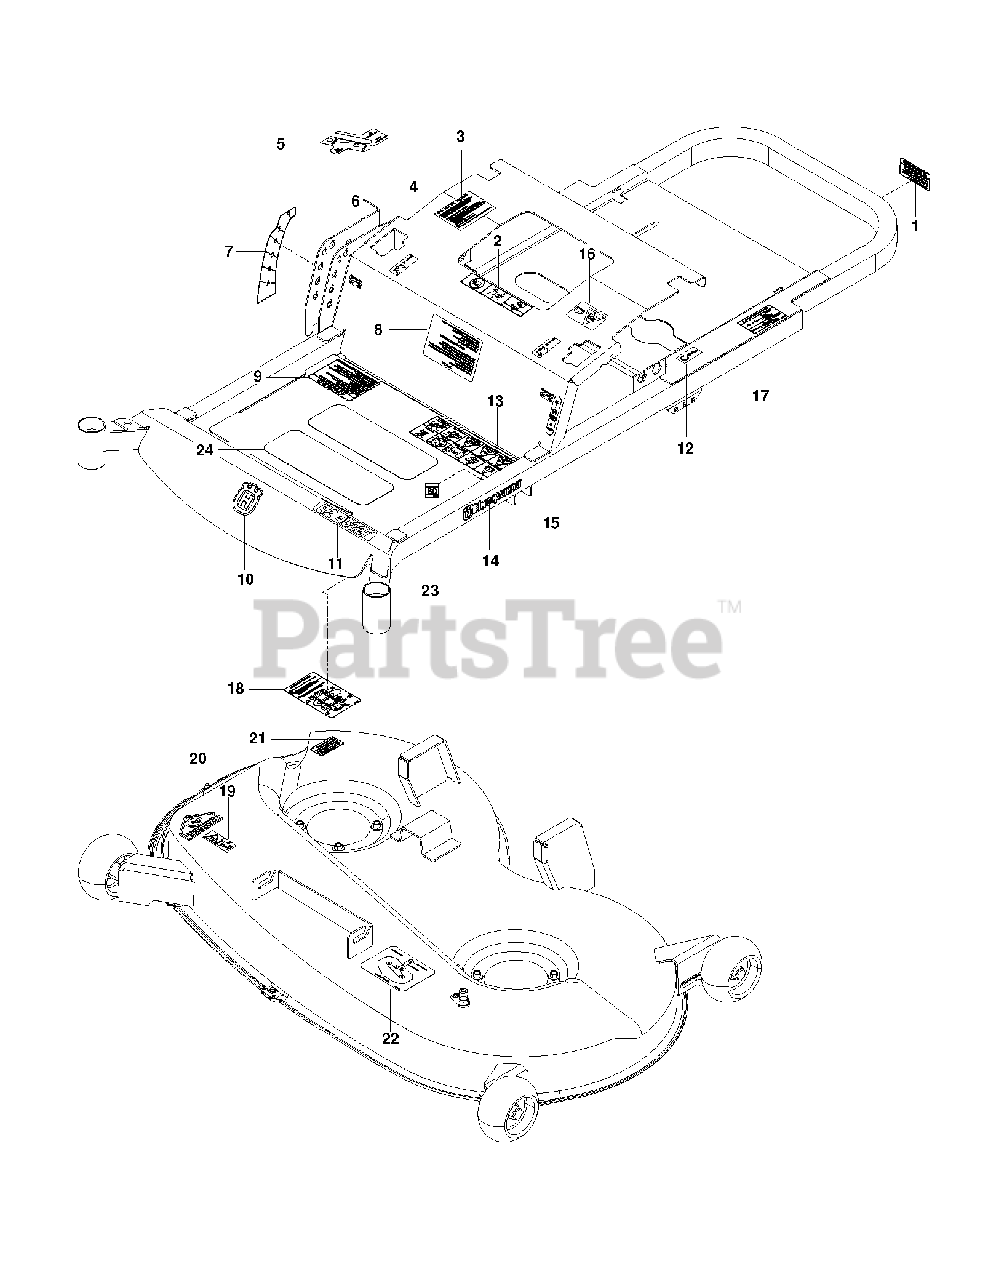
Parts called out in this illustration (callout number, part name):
1	DECAL, PROP. 65
2	EURO DECAL-BATTERY WARNIN6
3	DECAL, CUSTOMER RESPNSIBILITY
4	DECAL, MOTION CONTROL
5	DECAL, CTRL PANEL, HUSQ
6	DECAL, F.S.T.
7	DECAL, DECK HEIGHT, HUSQ
8	DECAL, START
9	DECAL, WARNING
10	DECAL.AUGER.HUSQ.CROWN.SNOW
11	DECAL RZ4622T
12	DECAL, ECM, AUSTRALIA
13	DECAL, SAFETY WARNING
14	RP.DECAL.BADGE.170MM.TEXTLOGO
15	DECAL, PARK BRAKE
16	DECAL, EXITING MOWER
17	DECAL, DO NOT TOW
18	DECAL, SERVICE
19	DECAL, EURO SEVERING
20	DECAL, CPSC
21	DECAL, CAUTION
22	DECAL, BELT ROUTING
23	DECAL 80 DBA
24	ANTI-SKID PAD
